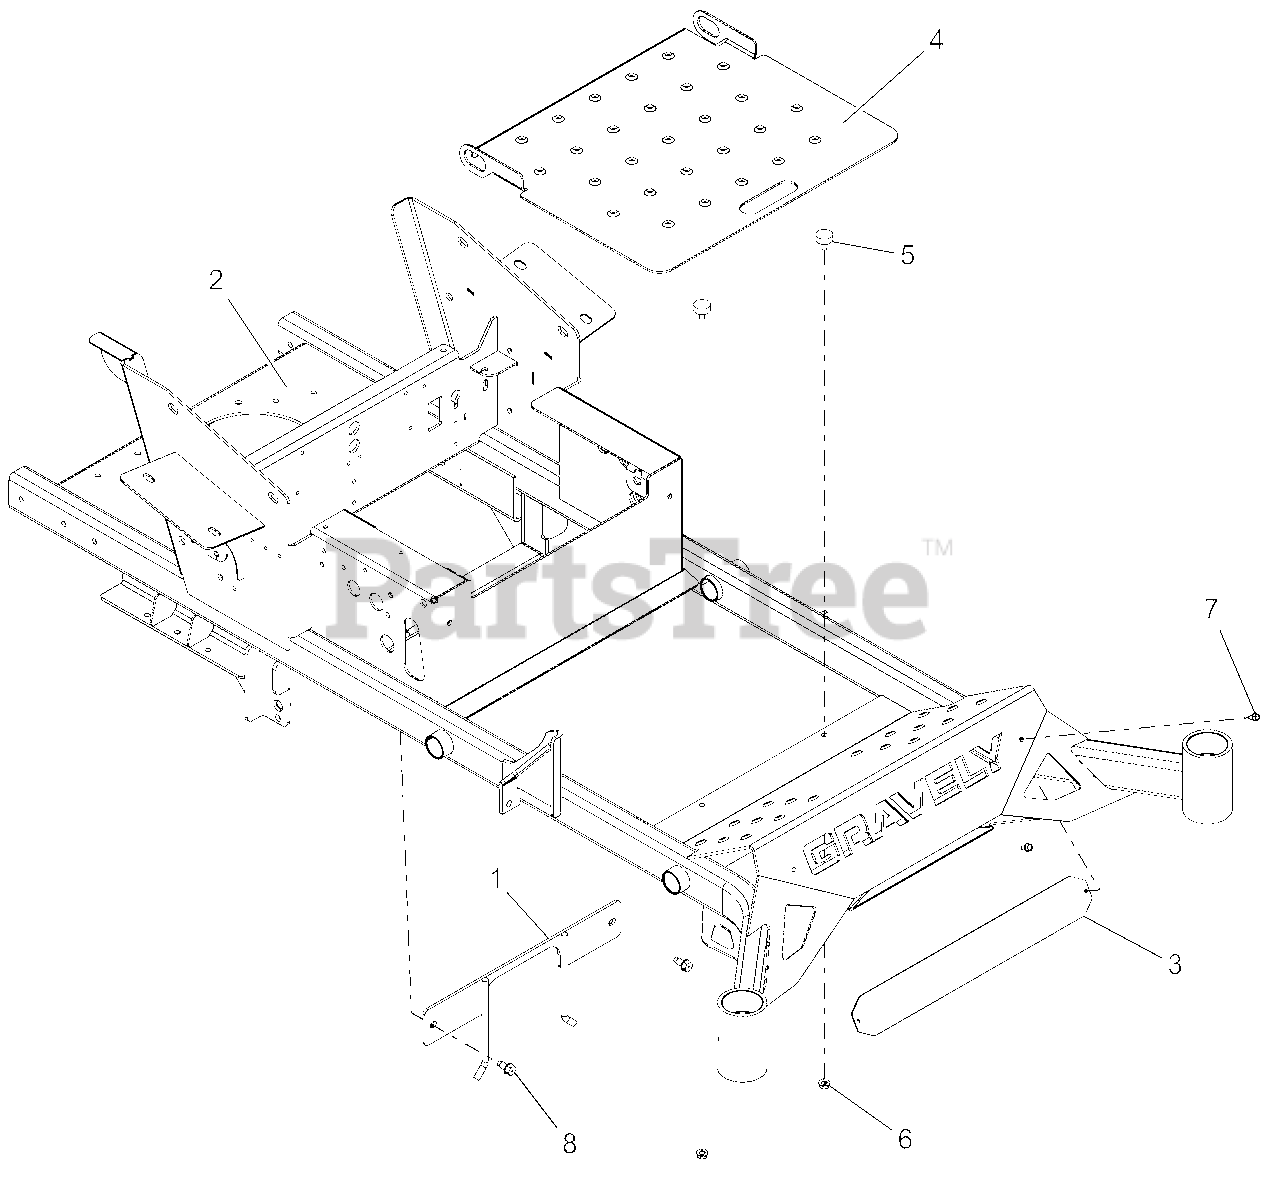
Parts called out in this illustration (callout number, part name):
1	PTO BELT FINGER WLDMT - BLK
2	PT/100 60" FRAME W/SAFETY DECL
3	BUMPER LOGO BACKING PLATE -BLK
4	PT/100 FOOT PLT W/SAFETY DECAL
5	BUMPER, RUBBER
6	@NUT-SPNLK-FLG .312-18 YWZC
7	SCR-TAP .25-20X.50 HWH TR YWZ
8	@SCR-TAP .38-16X.75 HWH TR YWZ
